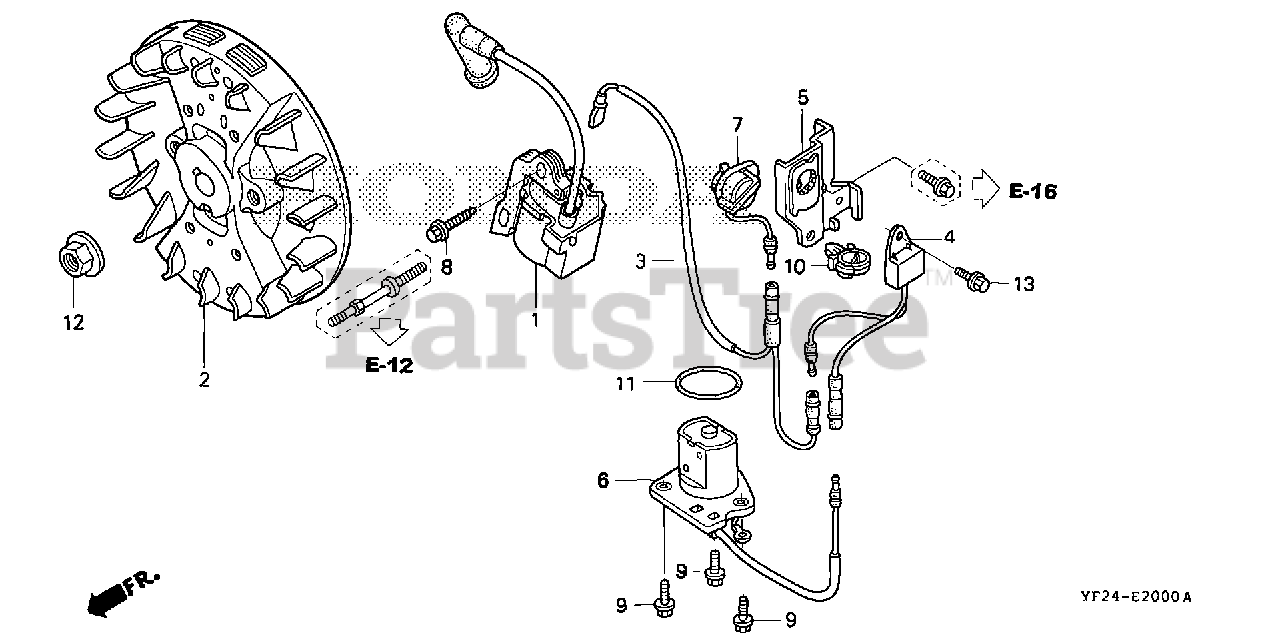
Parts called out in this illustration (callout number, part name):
1	COIL ASSY., IGNITION
3	WIRE, STOP SWITCH
4	ALERT UNIT, OIL
5	BRACKET, STOP SWITCH
6	SWITCH ASSY., OIL LEVEL
7	SWITCH ASSY., ENGINE STOP
8	BOLT, FLANGE (5X20)
9	BOLT, FLANGE (5X14)
10	CLIP, HARNESS
11	O-RING (34.6X2.5)
12	NUT, FLANGE (10MM)
13	BOLT, FLANGE (6X8)
